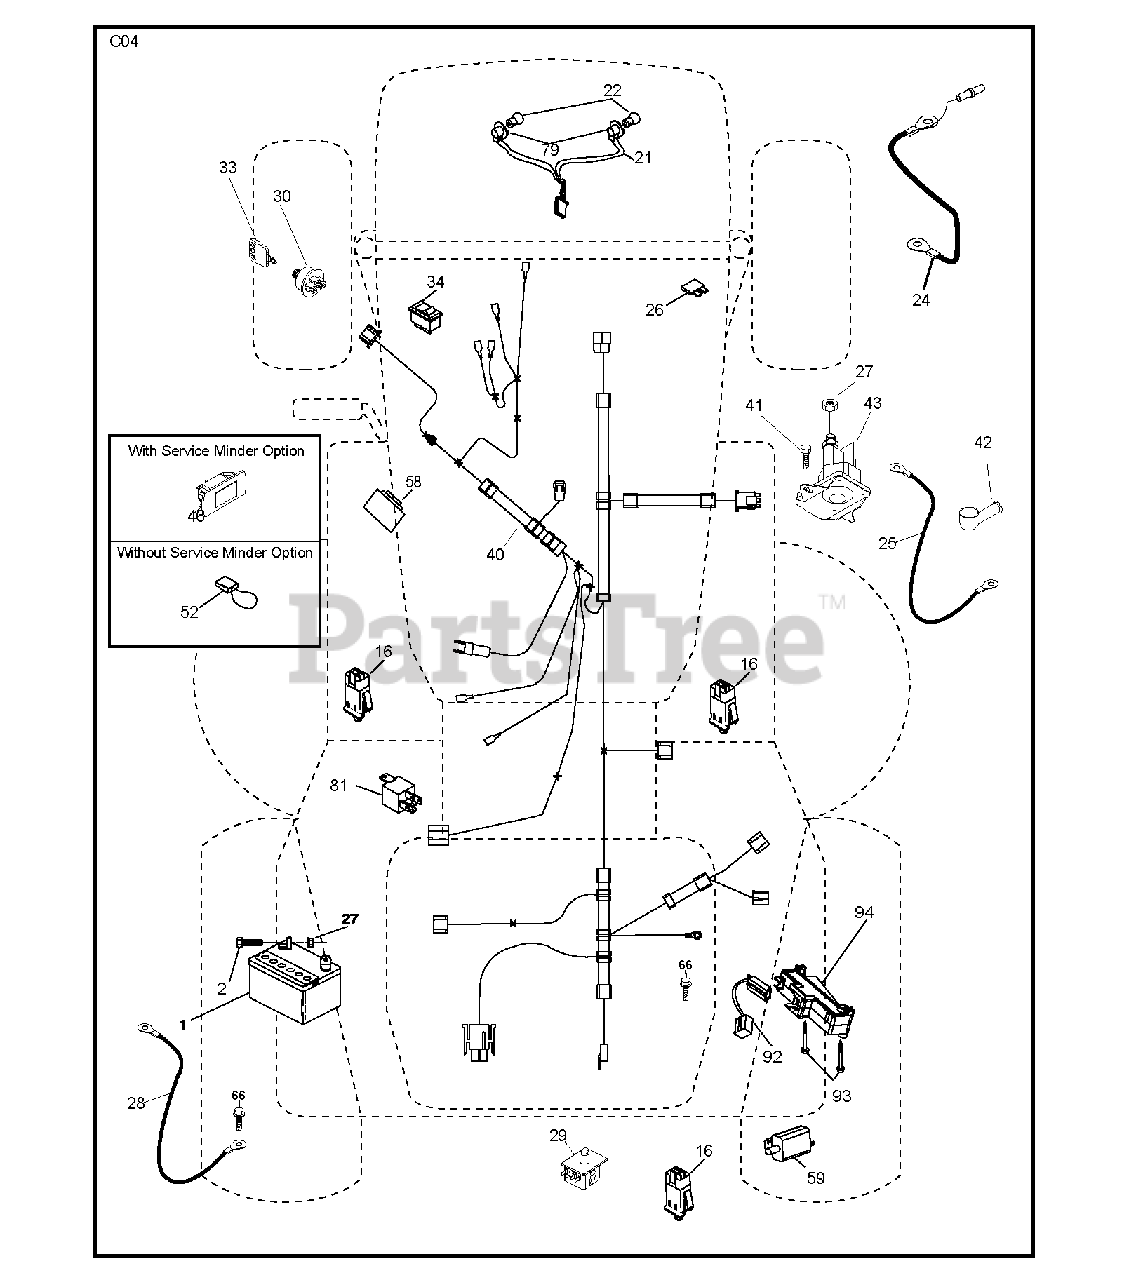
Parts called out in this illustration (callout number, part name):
1	REPL BY 532 12 38-99
16	SWITCH INTERLOOK PUSH-IN
21	HARNESS ASSY LIGHT
22	LIGHTBULB
24	CABLE BATTERY
25	CABLE BATTERY 6 GA. 11" RED
26	FUSE 20AMP
27	NUT
28	CABLE GROUND
29	SWITCH.SEAT.DP W/RAMPS
30	SWITCH.IGN.DELTA.W.LGH.ROS
33	KEY.CHAIN.BLISTER.PACK.GEN.INT
34	SWITCH LT
42	TERMINAL COVER
43	SOLENOID.W/BRASS.PLUNG
46	GUAGE.SRVCMNDR.HRMTR.
58	BUZZER
79	BULB HOLDER ASM.
81	RELAY.ASSY.T
92	HARNESS.PIGTAIL.CONSLE
93	SCREW.PLASTITE
94	MODULE.REVERSE.ROS
